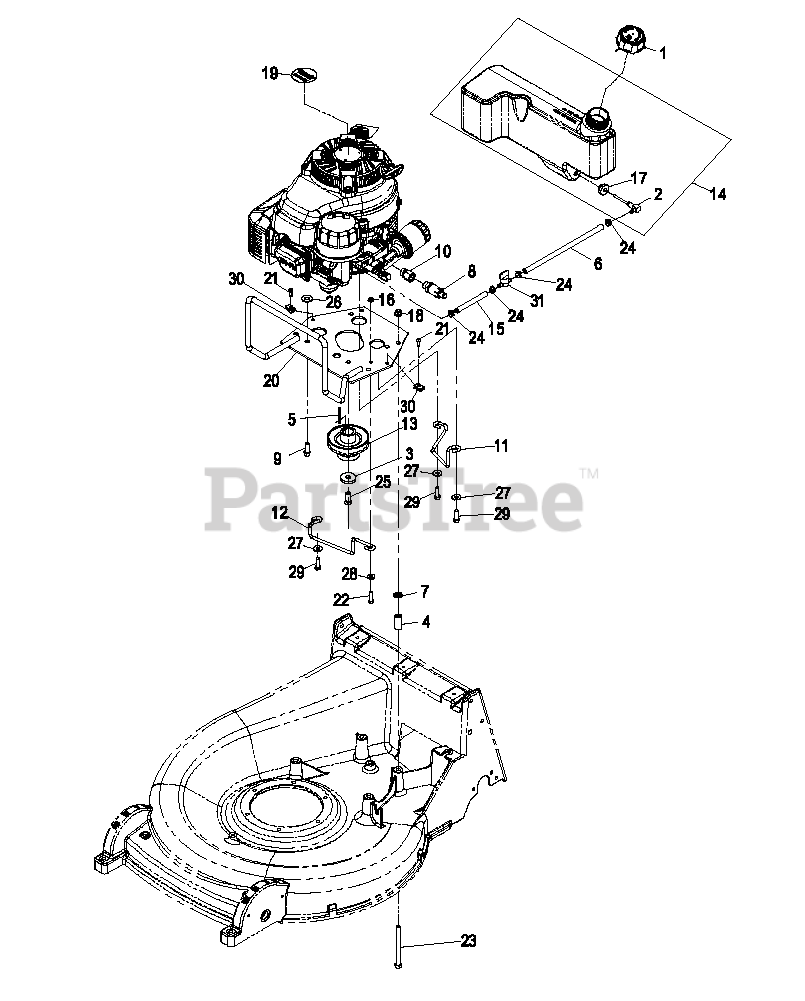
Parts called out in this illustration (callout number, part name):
1	CAP-FUEL
2	ELBOW-TANK, FUEL
3	WASHER-CLUTCH
4	BUSHING-LEVER, LIFT
5	KEY-SQUARE
6	HOSE-FUEL
7	RING-RETAINING
8	VALVE-DRAIN, OIL
9	SCREW-TAPTITE
10	ADAPTER
11	GUIDE-BELT, BLADE
12	GUIDE-BELT, TRANSMISSION
13	PULLEY-ENGINE
15	HOSE-FUEL
17	BUSHING
18	NUT-HF, NI
22	SCREW-HH
23	SCREW-HH
24	CLAMP-HOSE
25	SCREW-HH
26	WASHER-FLAT
27	WASHER-FLAT
28	WASHER-FLAT
29	SCREW-HH
30	Nut, Retainer-Panel 1/4-20
31	VALVE-FUEL
32	ASM,FUEL TANK
33	VALVE-FUEL
